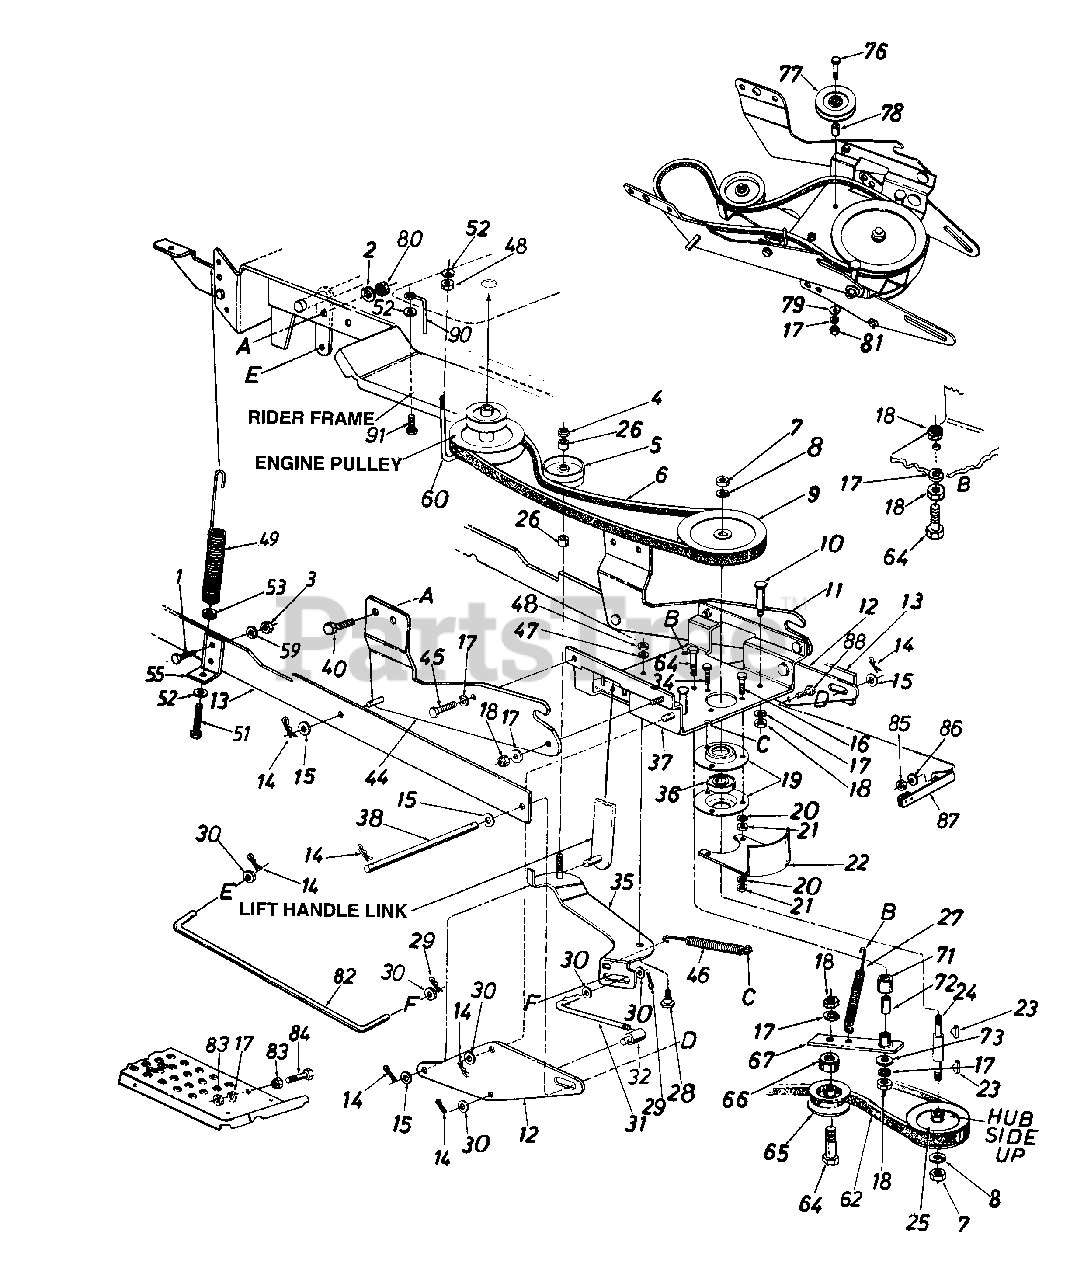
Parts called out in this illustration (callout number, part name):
1	Hex Bolt 1/4-28 x 1" Lg. Grade 5
2	L-Wash. 1/4" I.D.
3	Hex Nut 1/4-28 Thd.
4	Hex Cent. L-Nut 3/8-16 Thd.
5	Idler Pulley
6	V-Belt
7	Hex Jam Nut 5/8-11 Thd.
8	L-Wash. 5/8" I.D.
9	Pulley .627" I.D. x 6.5" O.D.
10	Shoulder Bolt
15	Fl-Wash.
16	Hex Bolt 5/16 x 1.25" Lg.
17	L-Wash. 3/8" I.D.
18	Hex Jam Nut 3/8-16 Thd.
19	Bearing Housing
20	L-Wash. 5/16" I.D.
21	Hex Nut 5/16-18 Thd.
22	Belt Guard
23	#Hi-Pro-Key 3/16" x 5/8" Dia.
24	Pulley Spindle
25	Pulley .628" I.D. x 5.56" O.D.
26	Spacer .383" I.D. x .503"
27	Extension Spring 5.25" Lg.
28	Shoulder Bolt
29	Cotter Pin 3/32" Dia.
30	Fl-Wash. .385" I.D. x .87"
31	Control Rod (Clutch)
32	Ferrule
34	Hex Sems Scr. 5/16-18 x .75" Lg.
35	Clutch Idler Brkt. Ass'y.
36	Ball Bearing
37	Channel Ass'y.
38	Lift Handle Shaft
40	Hex Self-Tap Scr. 1/4-20 x .75" Lg.
44	Channel Supporting Brkt. - L.H.
45	Hex Bolt 3/8-16 x 1" Lg.
46	Extension Spring
47	L-Wash. 5/16" I.D.
48	Hex Nut 5/16-18 Thd.
49	Helper Spring
51	Hex Bolt 5/16-18 x 1.5" Lg.
52	Bell-Wash. .345" 1.0. x .88"
53	Spring Insert
60	J-Bolt 5/16-18 Thd.
62	V-Belt
64	Hex Bolt 3/8-16 x 2.0" Lg.
65	Idler Pulley
66	Spacer .385" I.D. x .503"
67	Idler Arm Ass'y.
71	Spacer .380" I.D.
72	Spacer .3775" I.D.
73	Fl-Wash. 3/8" I.D. x 1" O.D.
76	Hex Bolt 3/8-16 x 2.5" Lg. (Grade 5)
77	Idler Pulley .38" I.D. x 3.06" O.D.
78	Spacer .385" I.D. x .76" Lg.
79	Fl-Wash. .39" I.D. x 1-3/4" O.D.
80	Hex L-Nut 1/4-20 Thd.
81	Hex Nut 3/8-16 Thd.
82	Clutch Control Rod
83	Hex Nut 3/8-24 Thd.
84	Hex Bolt 3/8-24 x 2.25" Lg.
85	Hex Nut 3/8-16 Thd.
86	Bell-Wash. 3/8" I.D.
87	Auger Brake Brkt. Ass'y.
88	Hex Bolt 3/8-16 x 5/8" Lg.
90	Belt Guard
91	Hex Bolt 5/16-18 x .75" Lg.
